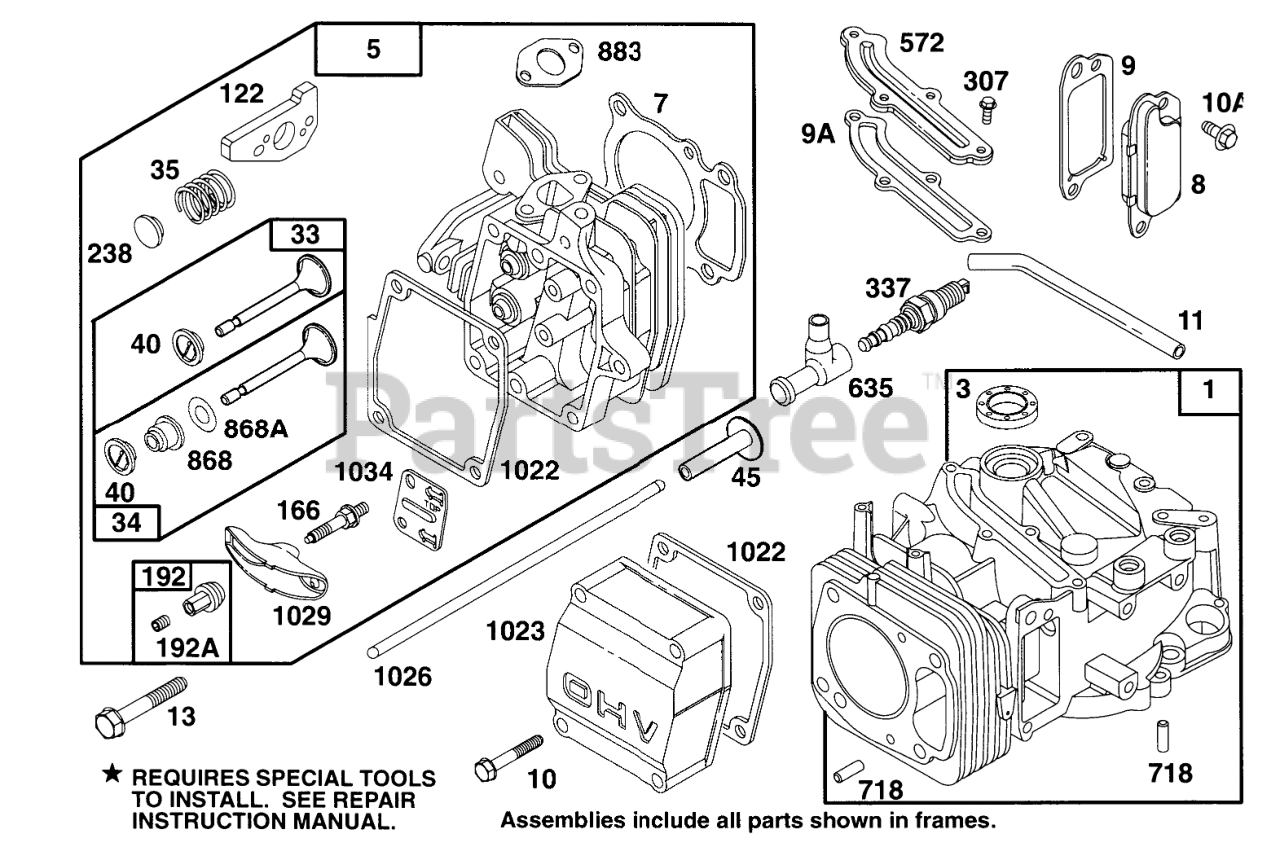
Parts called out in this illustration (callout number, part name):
1	CYLINDER ASSEMBLY
3	SEAL - OIL
5	CYLINDER HEAD
7	CYLINDER HEAD GASKET
8	Breather Assy
9	BREATHER GASKET
9A	GASKET-BREATHER
10	HEX HEAD SCREW
10A	HEX HEAD SCREW
11	TUBE - BREATHER
13	CYLINDER HEAD SCREW
33	EXHAUST VALVE
34	INTAKE VALVE
35	VALVE SPRING
40	SPRING RETAINER
45	VALVE TAPPET
122	ADAPTER ASSEMBLY
166	ROCKER ARM STUD
192	NUT - HEX SPECIAL
192A	SCREW SET
238	VALVE CAP
307	SCREW - SEM
337	PLUG-SPARK
572	BAFFLE - CYCLINDER
635	SPARK PLUG ELBOW
718	DOWEL - SLEEVE
868	SealAssy-Valve
868A	Seal-Valve
883	EXHAUST GASKET
1022	ROCKER COVER GASKET
1023	COVER - VALVE
1026	PUSH ROD
1029	ROCKER ARM
1034	PUSH ROD GUIDE
